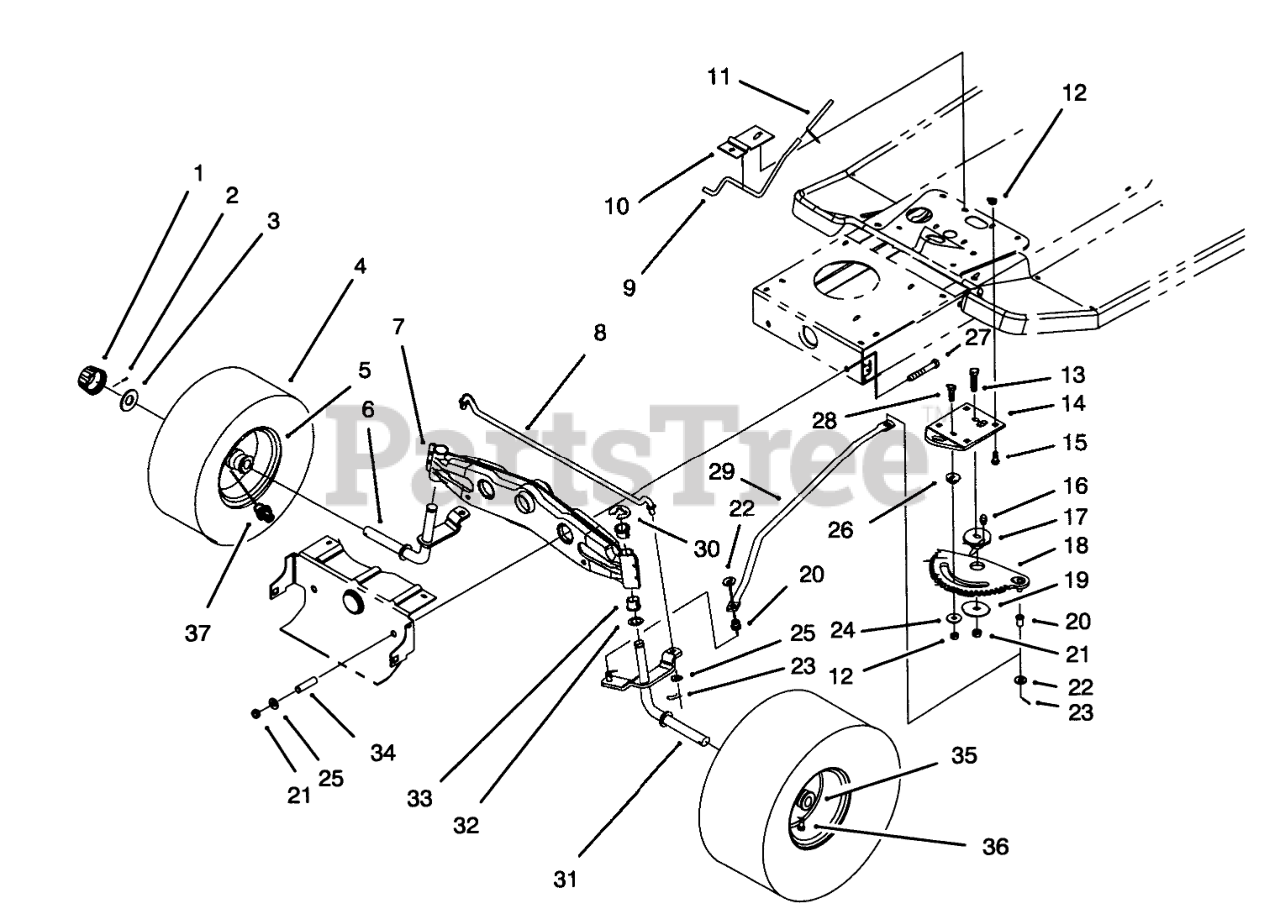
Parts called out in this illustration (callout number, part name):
1	CAP-HUB
2	PIN-COTTER
3	WASHER-PLAIN
4	TIRE 15 X 6.00 X 6
5	RIM ASM
6	Spindle-R.H.
7	Axle-Front
8	TIE ROD-STEERING
9	ROD-BRAKE, PARKING
10	Bracket-Parking Brake
11	GRIP-BRAKE, PARKING
12	NUT-LOCK, NI
13	SCREW-HH
14	Bracket-Steering Rack
15	BOLT-CARR
16	FITTING-GREASE
17	BUSHING-ECCENTRIC
18	RACK-STEERING
19	WASHER-BEARING
20	BUSHING-FLANGED, NYLON
21	NUT-LOCK, NI
22	WASHER-FLAT
23	PIN-COTTER
24	WASHER-PIVOT
25	WASHER-FLAT
26	SPACER-RACK, STEERING
27	SCREW-HH
28	SCREW-HH
29	LINK-DRAG
30	E-RING
31	Spindle-L.H.
32	WASHER-THRUST
33	BUSHING
34	SPACER
35	BEARING-WHEEL
36	Valve Stem w/Cap
37	FITTING-GREASE
